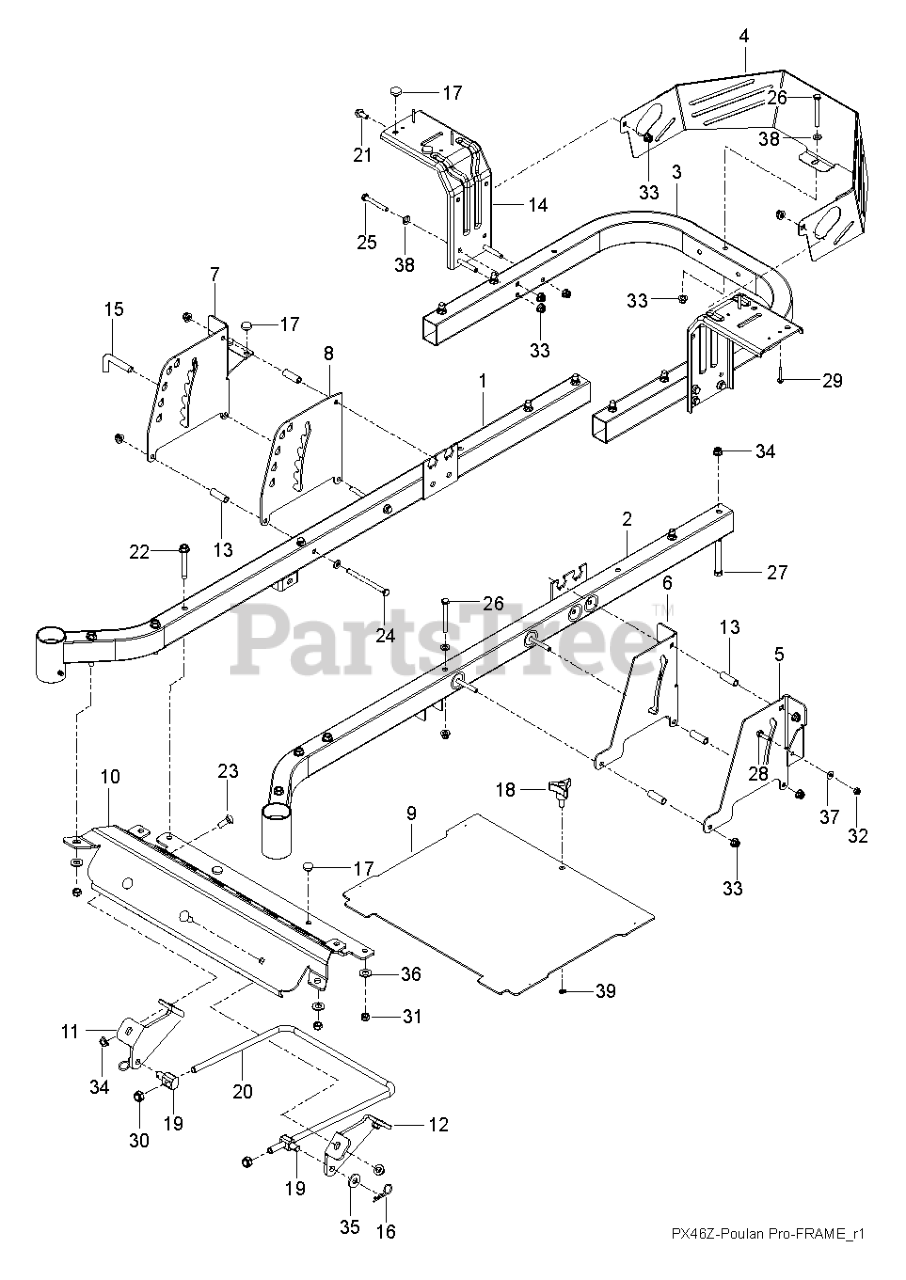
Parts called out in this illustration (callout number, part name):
1	FRAME TUBE RZ MAIN WELDMENT RI
2	FRAME TUBE RZ MAIN WELDMENT LE
3	FRAME.PNT.REAR.TUBE.BLACK
4	HEAT SHIELD, RZ, 21IN FRAME BL
5	PLATE, OUTER BRAKE, BLACK
6	PLATE, BRAKE LATCH, BLACK
7	PLATE.DECK HEIGHT.PNT.431.RZ
8	PLATE, DECK HEIGHT, BLACK
9	PLATE, FOOT W/DECALS, BLK
10	FOOT REST, MED BLK
11	MOUNT.STRUT.RH.431
12	MOUNT.STRUT.LH.431
13	SPACER.334.ID.5.OD.1.5.L
14	FENDER.SUPPORT.PNT.X431
15	PIN.DECK.HEIGHT.RZ
16	HAIRPIN #4
17	GROMMET, BUMPER
18	KNOB W/STUD
19	SWIVEL.TRUNION.LINK.DECK.FRONT
20	LINK, FRONT SUSP.
21	HHFS 5/16-18 X 3/4
22	HHFS 3/8-16 X 2-3/4 GR5 ZD
23	RHSNB 3/8C X 1
24	HCS 5/16C X 4
25	Bolt Fin Hex 5/16-18 x 2-1/4 (AYP part number)
26	Bolt Fin Hex 5/16 - 18 UNC x 2.75 (AYP part number)
27	BOLT.HEX.FIN.3/8-16 X 3.GR5
29	SCR #10-12X1-1/2HEX WASH HD ZD
30	7/16-14 HEX NUT W/NYL RING ZD
31	NUT HEX 3/8-16 NYLON, THIN
32	NUT 1/4-20 NYLOC
33	5/16-18 NYLOC FLANGE NUT
34	NUT 3/8-16 HEX FLG NYLOC ZD
35	WASHER
36	WASHER 3/8 FLAT
37	Washer 9/32 x 5/8 x 16 Gauge (AYP part number)
38	Washer, Nut Lock Hex w/Ins. 5/6-18 (AYP part number)
39	WASHER 5/16"
